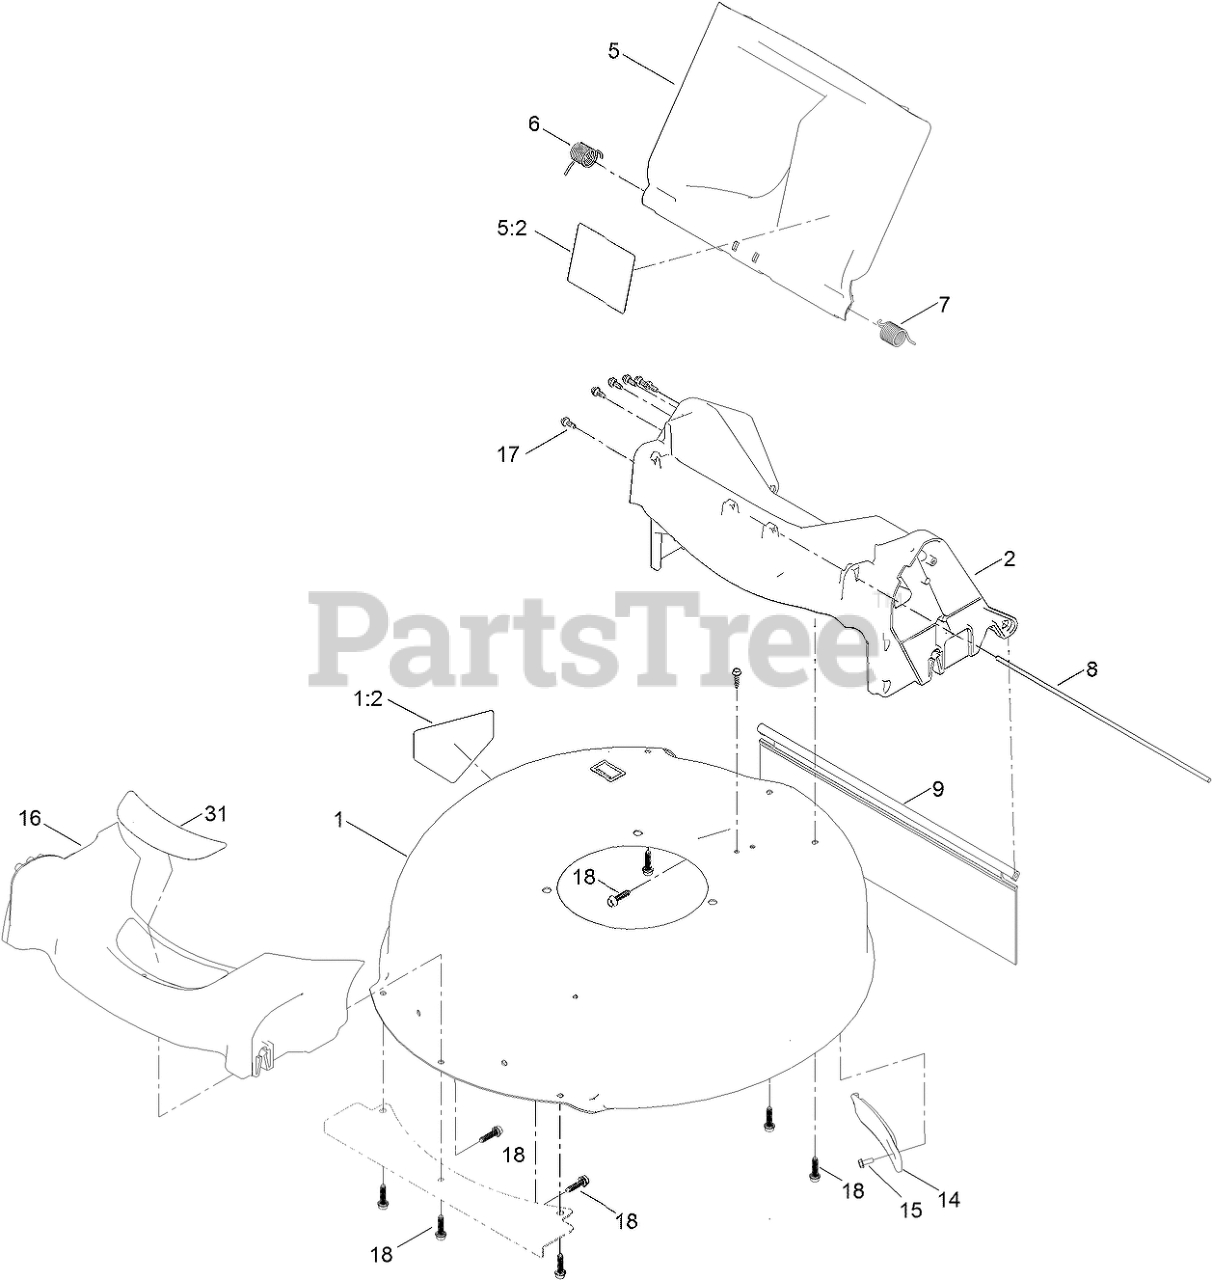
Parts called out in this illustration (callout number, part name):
1	HOUSING ASM
1:2	DECAL-DANGER
2	CHUTE ASM
5	REAR DEFLECTOR ASM (60V)
5:2	DECAL-WPM WARNING, 60V
6	SPRING-TORSION
7	SPRING-TORSION
8	ROD-DOOR
9	SHIELD-TRAILING
14	COVER-BELT
15	SCREW-TAPTITE
16	BUMPER
18	SCREW-FLANGE, PLASTIC
31	DECAL-DECK
